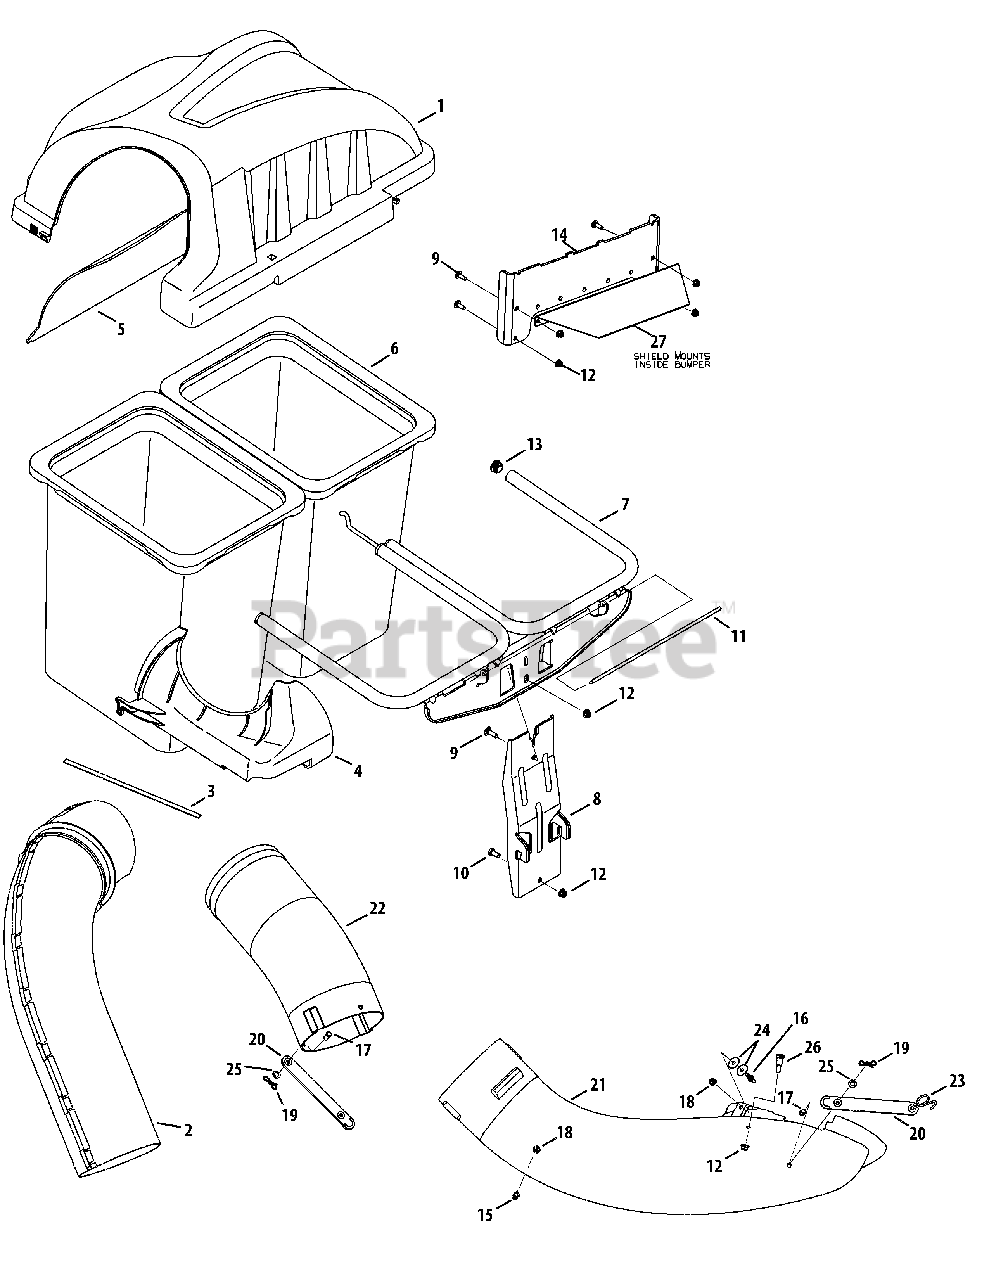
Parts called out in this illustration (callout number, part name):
1	Cover Assembly, Bag, Double
2	Chute Assembly, Bagger, Upper, 32in
3	Foam, Tape, .75 Wide X .125 Thick
4	Support, Bagger, Upper Chute
5	Screen, Bagger
6	Bag Assembly, Grass bag, Cub
7	Support Assembly, Bag, Double
8	Bracket Assembly, Bagger, Vert Support
9	Screw, Carriage, 5/16-18, 1.00
10	Hex Head Screw, 5/16-18, .75, Gr5, Std
11	Pin, Cover Hinge, Bagger, Double
12	Nut, Flange lock, 5/16-18, Nylon
15	Pin, Grass catcher, 1/4-20
16	Attachment Pin, 1/4 x 0.66 Lg.
17	Clevis Pin, 5/16 x .75 Lg.
18	Nut, Flange Lock, 1/4-20
19	Bow-Tie Cotter Pin, 72
20	Chute Strap, 6.00 Lg.
21	Bagger Discharge Chute, Elbow
22	Chute Extension
23	Torsion Spring Hook
24	Wash, Bell, .265 X .938 X .120
25	Wash, Bell, .344 X .620 X .033
26	Shoulder Screw, .437 x .54
27	Muffler Shield
